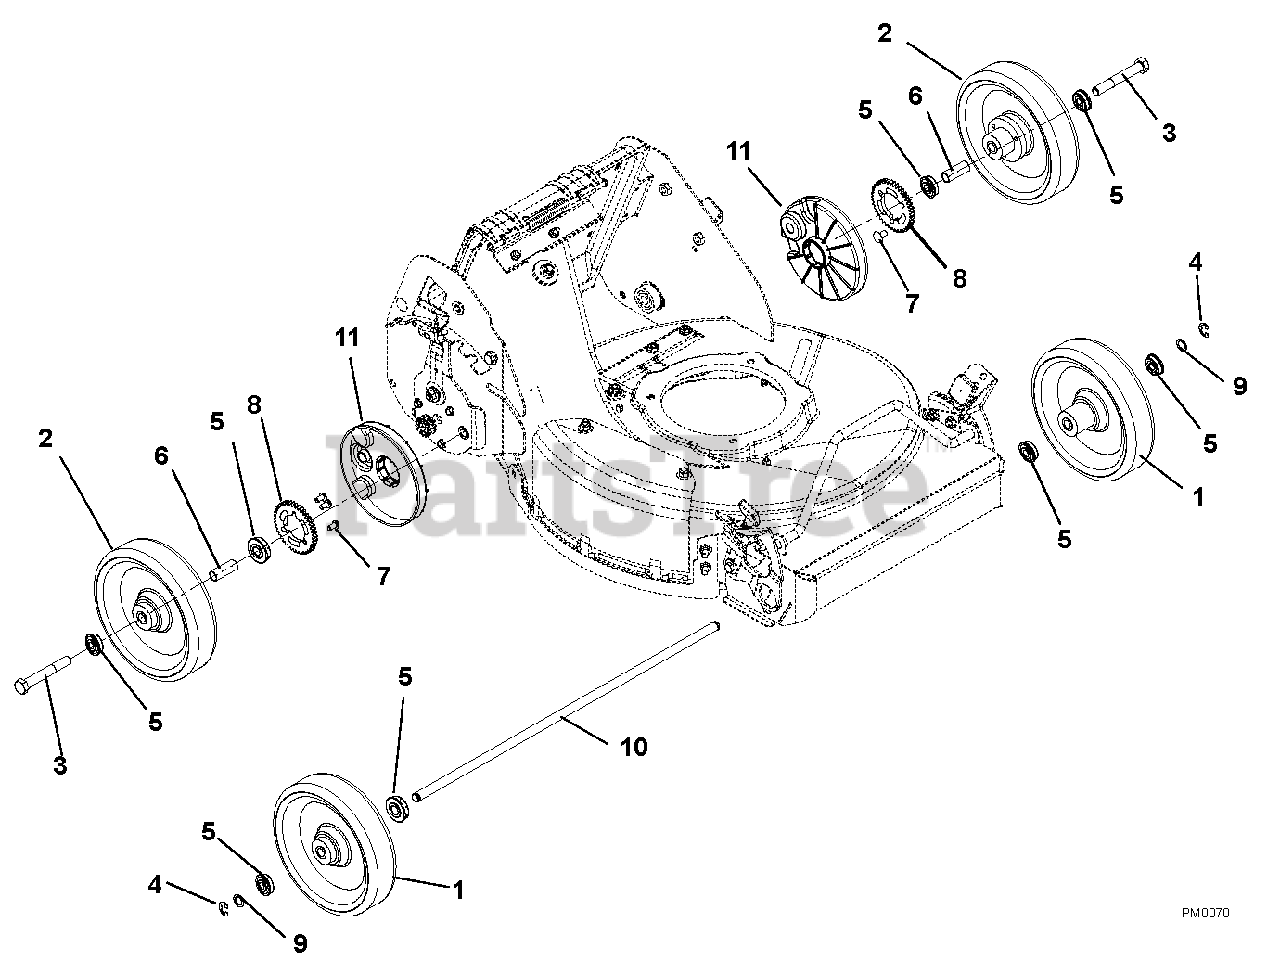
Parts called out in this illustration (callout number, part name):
1	Tire, 8 x 1.75 Commercial Front (Includes item 5)
2	Rear Wheels (Includes items 5 and 6)
3	5/8 Shoulder,.50-13 Grade 8
4	Ring, Retaining, External .500 x .042
5	Bearing, Ball .50 x 1.375 x .437 Sealed
6	Spacer, Wheel
7	Screw, Tapping 1/4-20 x 3/4
8	Gear, Wheel
9	Washer, .500 x .750 x .020 Thrust
10	Axle Shaft
11	Cover, Wheel
